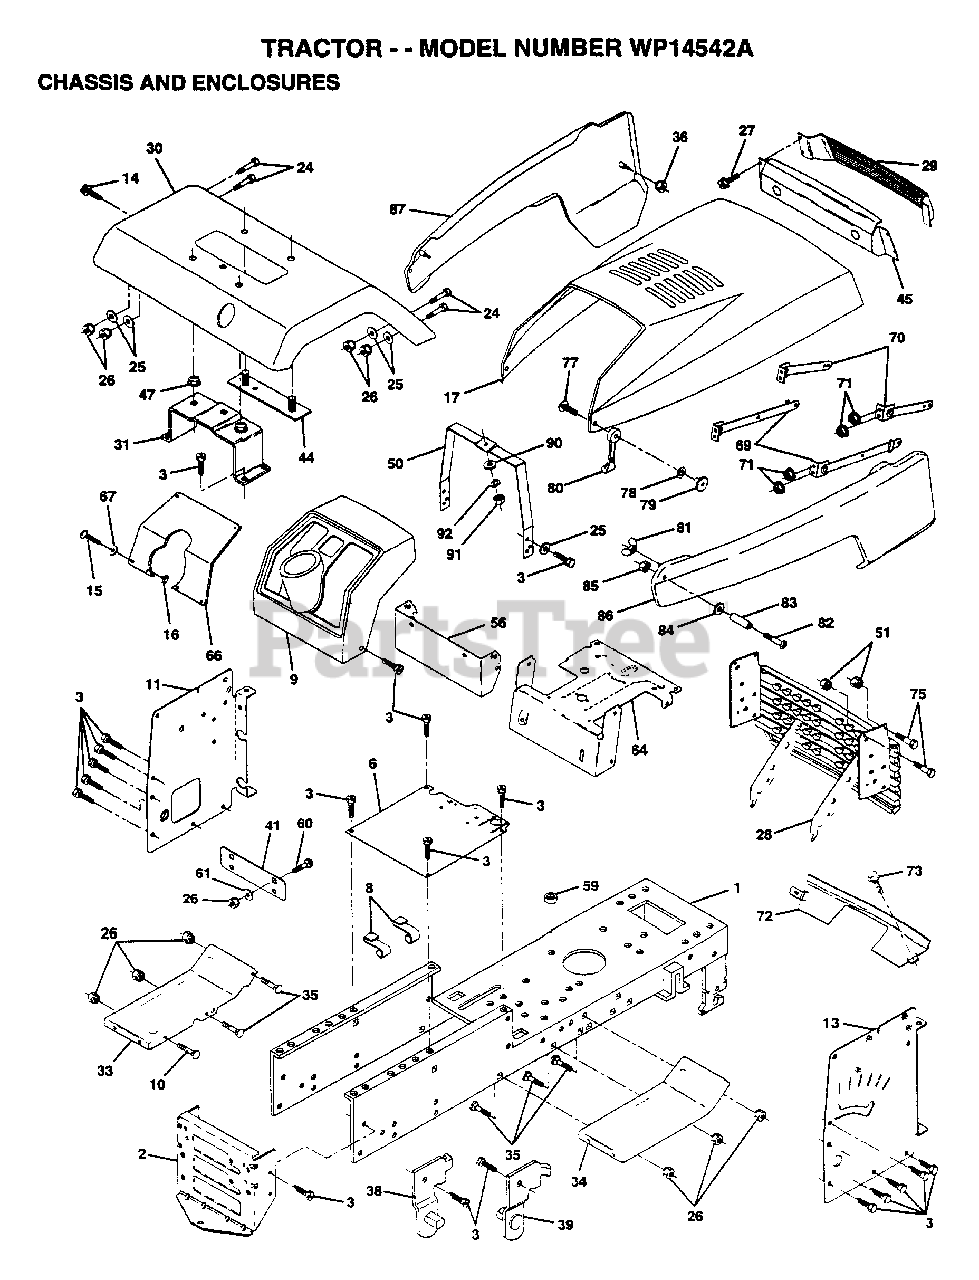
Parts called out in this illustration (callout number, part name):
1	CHASSIS.WLD.11GA
3	SCREW
8	"CLIP,INSULATOR"
9	DASHBOARD BLACK
11	PANEL.DASH.LH.
13	PANEL.DASH.RH.
14	SCREW LT
15	SCREW
24	BOLT
25	WASHER
26	NUT
29	LENS.BAR.CLEAR
30	FENDER.PNT.
31	BRKT.ASM.FENDER
33	FOOTREST.LH.LT/GT
34	FOOTREST.RH.LT/GT
35	BOLT
36	PAL NUT LT
38	BRACKET ASM LH
39	BRACKET ASM RH
44	STRAP ASM FENDER
47	NUT-PUSH YT
50	DASH.SUPT.YP/HUSQ
56	DASH.EXT.PNT.
66	PLATE.DASH.SILKSC
67	WASHER
71	NUT HXKEP 1/4X20
72	STRAP.GRILLE.PNT.
73	SCREW CRT
77	SCREW
78	LOCKWASHER
79	WELDNUT
80	HOOD LATCH T
82	SCREW
83	SPACER LT
84	WASHER
87	"PANEL,SIDE LH"
90	WASHER PM
92	LOCKWASHER
